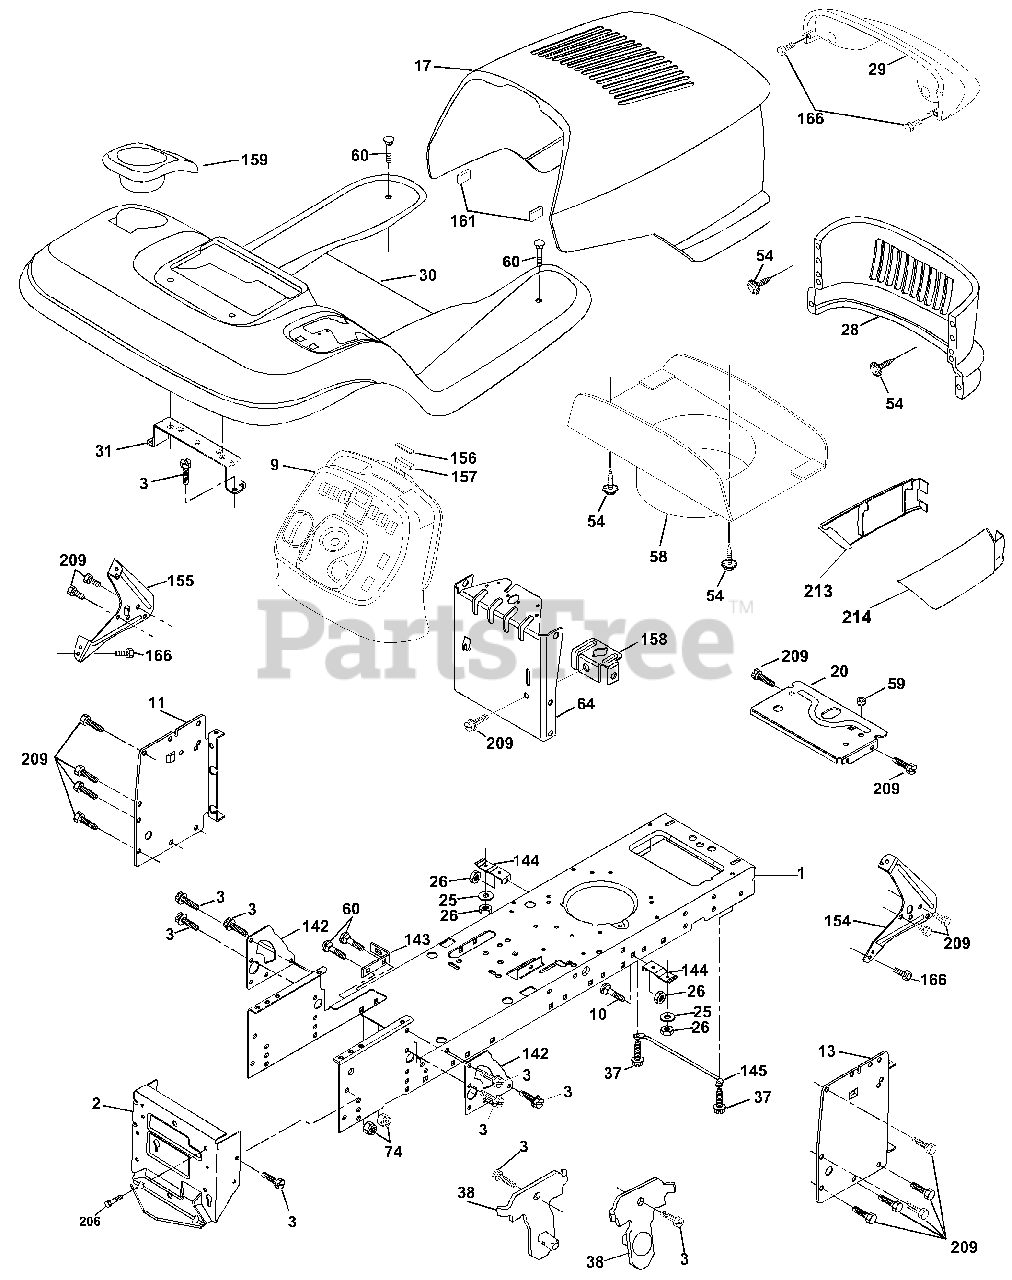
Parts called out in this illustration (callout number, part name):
1	Chassis
2	Drawbar
3	Screw 3/8-16x3/4
9	Dash
10	Bolt Carriage 3/8-16 x 1
11	Panel Dash Lh
12	Clip Tinnerman
13	Panel Dash Rh
17	Hood
18	Bumper Hood
20	Plate Battery
23	Bushing
24	Bolt Fin Hex 3/8-16 x 1 Gr 5
25	Washer 13/32 X 13/16 X 12 Ga
26	Nut Lock Hex W/Ins 3/8-16 Unc
28	Grille
29	Lens
31	Bracket Fender
33	Footrest Pnt Lh
34	Footrest Pnt Rh
35	Bolt Rdhd Sht Sqnk 3/8-16 x 3/4
37	Screw Thdrol 6/16-18 x 1/2 TYT
38	Bracket, Asm. Pivot Mower Rear
44	Strap Asm Fender
49	Screw Hexwsh Thdrol 1/4-20 x 3/4
50	Brace Support Dash P/L
51	Nut Lock Hex W/Ins 1/4-20
52	Washer 9/32 x 7/8 x 16 Ga.
53	Bracjet Grukke Lh
54	Screw Hex Wshd 8-18 x 7/8
55	Bracket Grille Rh
57	Bolt Hex 1/4-20 x 3/4
58	Duct Hood
59	Bushing Snap
60	Bolt Rd Hd Sqnk 3/8-16 Unc x 3/4
64	Dash Lower
68	Nut Keps Hex 1/4-20 Unc
74	Nut Crownlock 3/8-16 Unc
142	Plate Reinforcement STLT
143	Bracket Swaybar Chassis
144	Bracket Footrest
145	Rod Pivot Chassis/Hood
154	Bracket Dash Rh
155	Bracket Dash Lh
156	Striker Plate
157	Magnet Stealth
158	Bracket Parking Brake
159	Cupholder
161	Extrusion Bumper
166	Screw Hw Hd Hi-Lo #13-16 x 3/4
195	Panel Pnt Fender YT/GT
196	Screw Tap Tite 1/4-20 x 1/2
206	Bolt Shoulder 5/16-18
207	Screw Thdrol 5/16-18 x 1/2
208	Screw Thdrol 3/8-16 x 1/2
209	Screw Hexwsh Thdrol 3/8-16 x 3/4
212	Insert Lens Reflective
213	Skirt Grille Lh
214	Skirt Grille Rh
